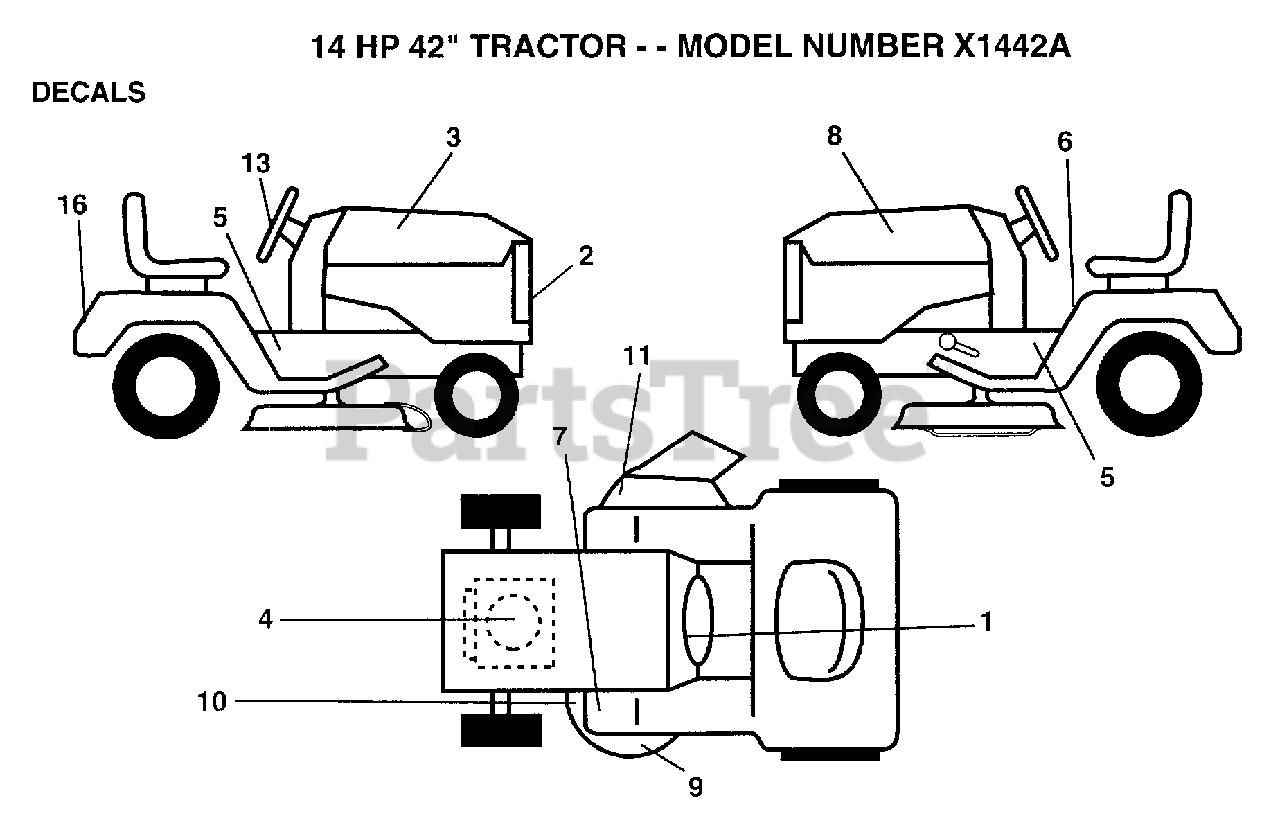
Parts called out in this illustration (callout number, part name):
2	"DECAL,GRILL "
3	"DECAL,HOOD RH "
4	DECAL.ENG.272613
5	DECAL.CHASS.6SP
6	DECAL CAUTION
7	DECAL T
10	DECAL
11	"DECAL, WARNING"
13	"DECAL,STR WHL "
16	"DECAL,LOGO"
